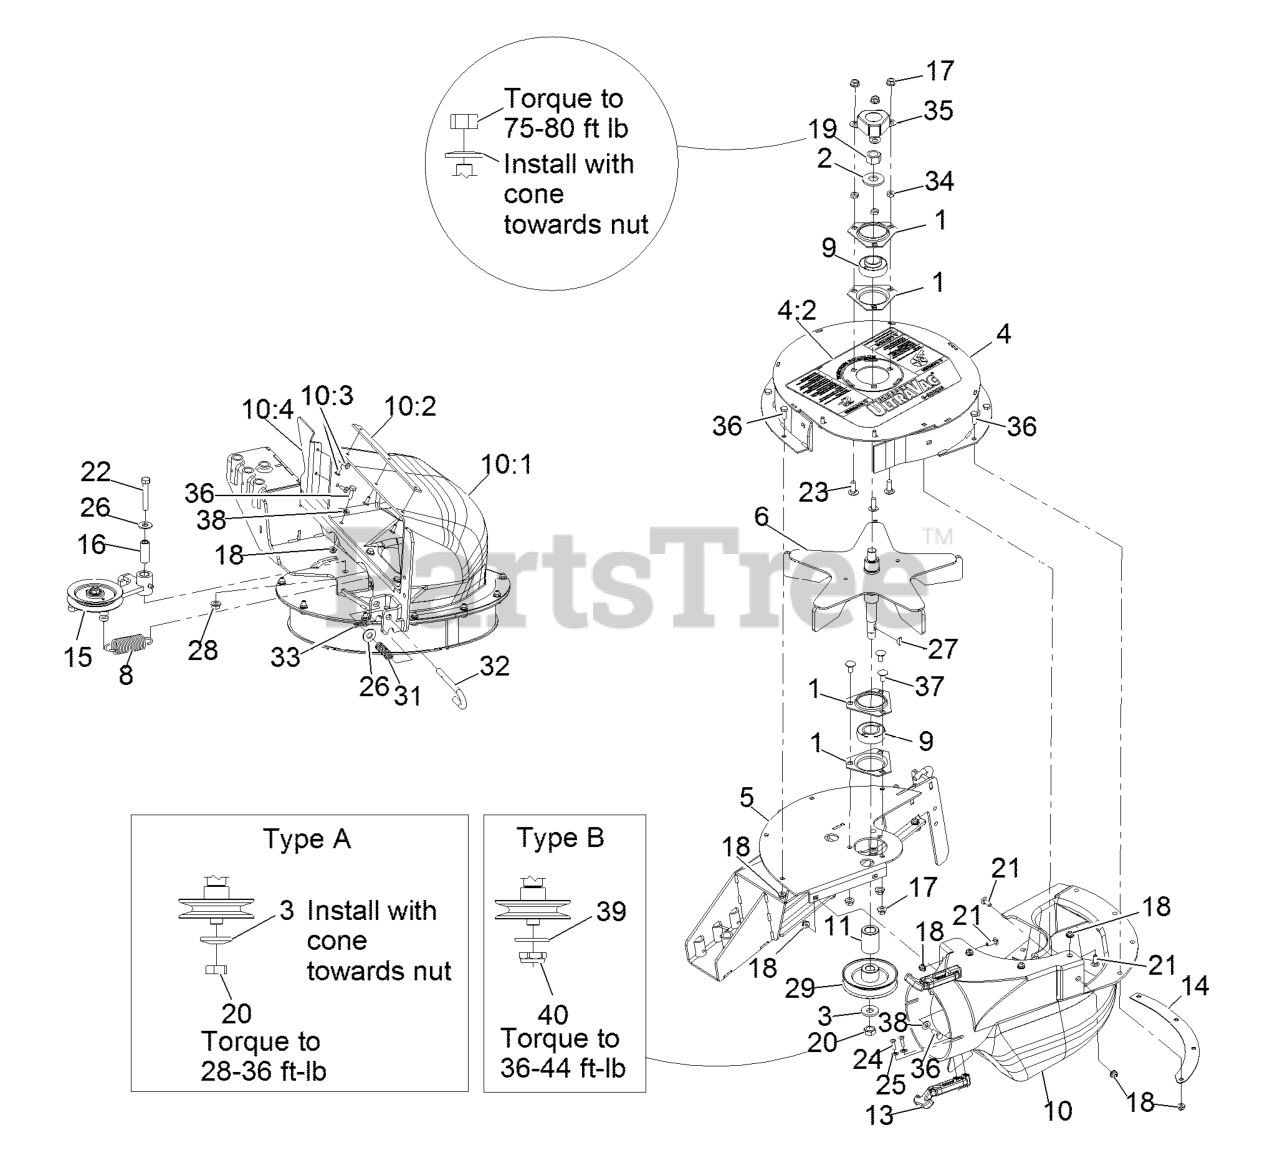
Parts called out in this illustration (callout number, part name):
1	HOUSING-FLANGE
2	WASHER-SPRING
3	WASHER-SPRING
4	UPPER HOUSING W/DECAL
4:2	DECAL-BLOWER WARNING
5	BLOWER FRAME ASM
6	IMPELLER
8	SPRING-IDLER
9	BEARING
10	BLOWER CHUTE ASM
10:1	CHUTE-BLOWER, SMALL
10:2	PLATE-REINFORCEMENT
10:3	RIVET-BLIND
10:4	PLATE-FILLER
13	LATCH-RUBBER
14	PLATE-BACKING
15	Asm, Idler
16	BUSHING
19	NUT-HEX
20	NUT-JAM
21	BOLT-CARR
22	SCREW-HH
23	BOLT-CARR
24	SCREW-PPH
25	WASHER-FLAT
26	WASHER-FLAT
27	KEY-WOODRUFF
28	NUT-HHF, WHIZ
29	SHEAVE-BLOWER
31	SPRING-COMPRESSION
32	PIN-LATCH
34	NUT-JAM
35	COVER-NUT
36	SCREW-HH
37	SCREW-CARR
38	WASHER-FLAT
39	WASHER-FLAT
40	NUT-LOCK, NI
